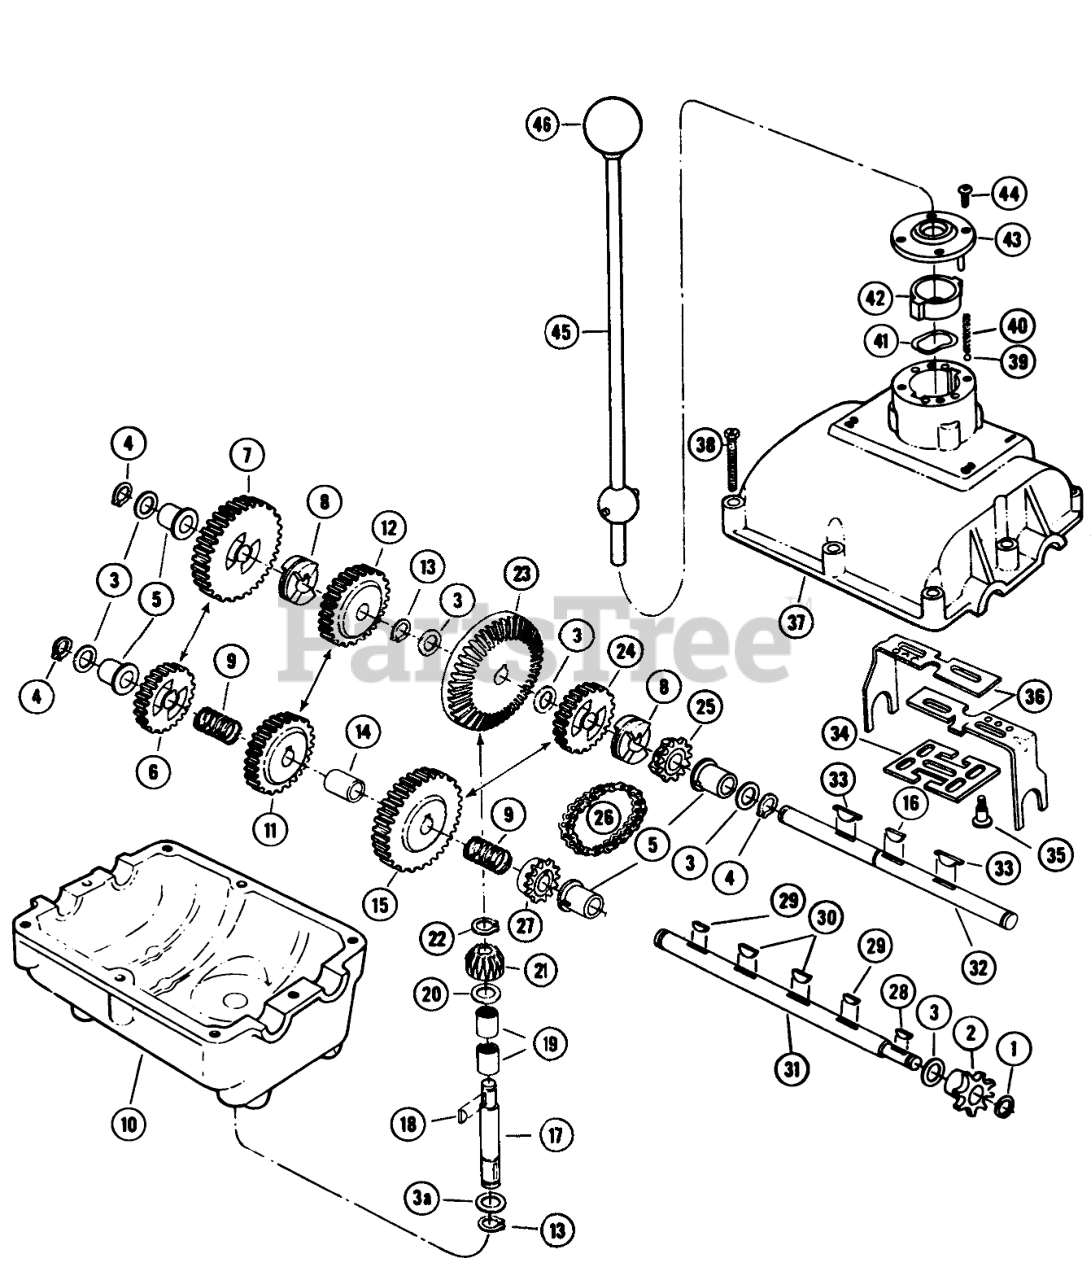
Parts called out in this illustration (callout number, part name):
1	Retaining Ring (#5108-50)
2	Sprocket
3	Washer (.030")
3	Washer (.040")
3	Washer (.050")
4	E-RING
5	Flange Bearing
6	20-T Gear (with keyway)
7	30-T Gear (without keyway)
8	Clutch Collar
9	Compression Spring
10	Lower Housing
11	Gear (with keyway)
12	Gear (without keyway)
13	RING-SNAP, EXTERNAL
15	Gear (with keyway)
17	Input Shaft
19	Needle Bearing
20	Thrust Washer
21	Bevel Pinion
22	Ring-Snap
23	Bevel Gear
24	Gear (without keyway)
25	Sprocket (without keyway)
27	Sprocket (with keyway)
31	Output Shaft
32	Drive Shaft
33	Key (special)
34	Shifter Lock-Out Plate
35	Shoulder Screw
36	Shifter Fork
37	Upper Housing
39	Detent Ball
40	Detent Spring
41	Wave Washer
42	Nylon Insert
43	Nylon Cover
45	Shifter Handle Assembly
46	Shifter Knob
